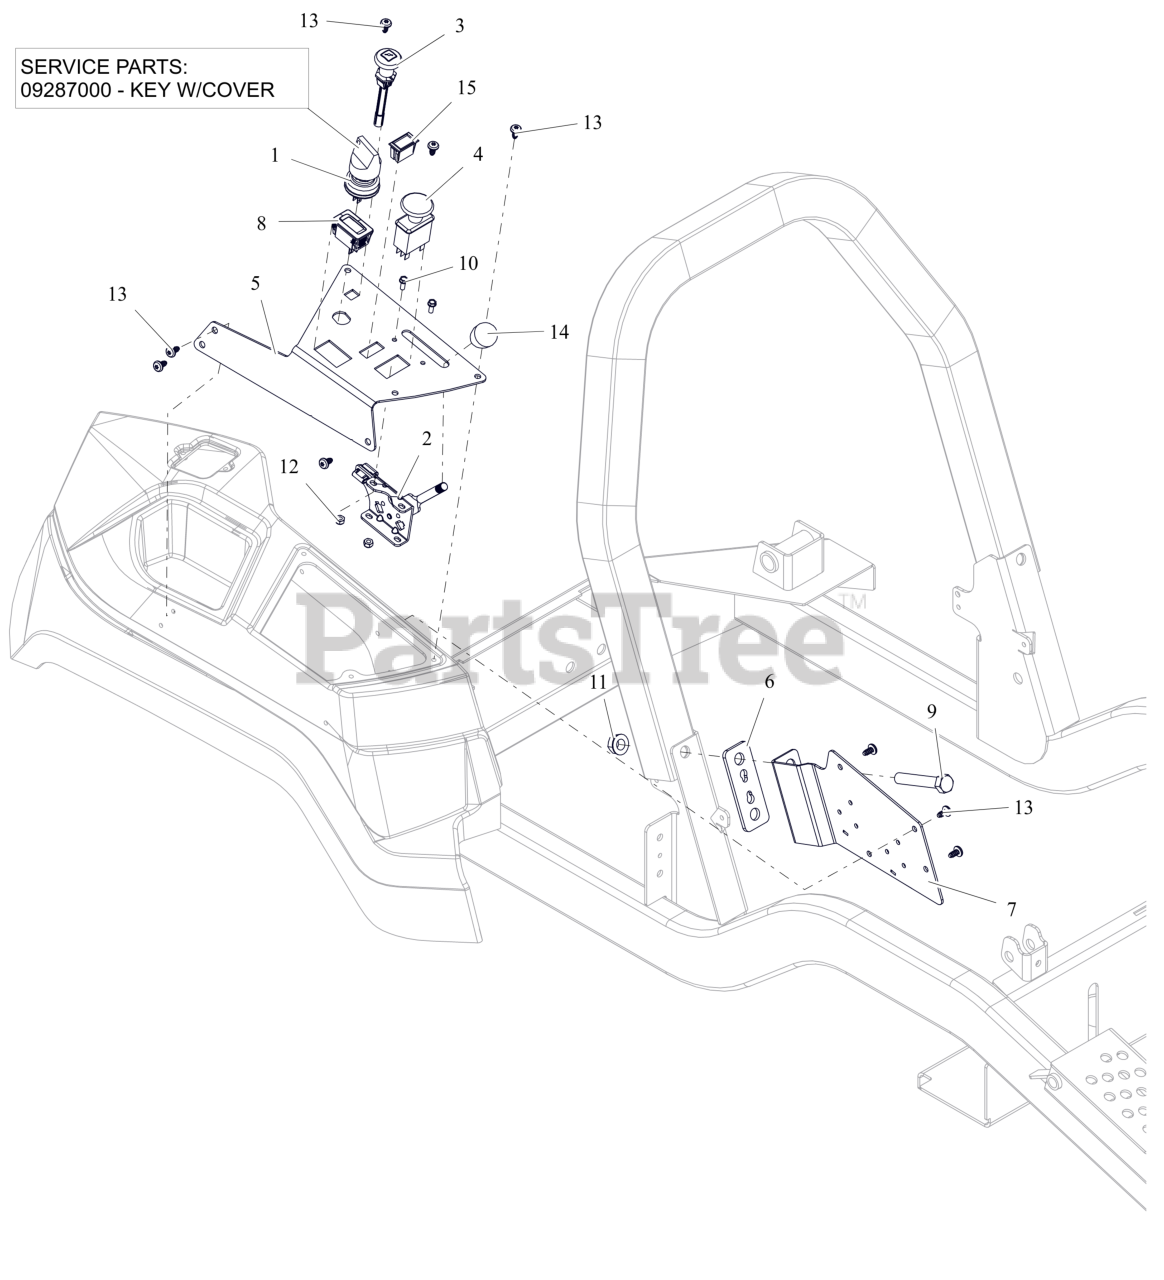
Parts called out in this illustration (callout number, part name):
1	SWITCH, IGNITION
2	CABLE, PRO THROTTLE CONTROL
3	CABLE - CHOKE, SNAP-IN
4	SWITCH, CLUTCH
5	PLATE, APEX CONTROL PANEL
6	PLATE, CONTROL PANEL SPACER
7	BRKT, FENDER/RELAY MOUNTING
8	HOUR METER
9	BLT, HEX .50-13X3.00 G5 ZCC
10	BLT, HWH #10-24X.50 ZCC
11	NUT-LK-CTR-FLG .500-13 GG ZCC
12	NUT-LK-NYL #10-24 G2 ZCC
13	SCR-PAN .25-15X.50 6L H/LZB500
14	KNOB-CONTROL-BLACK .38-16X.50
15	SWITCH,BLANK
